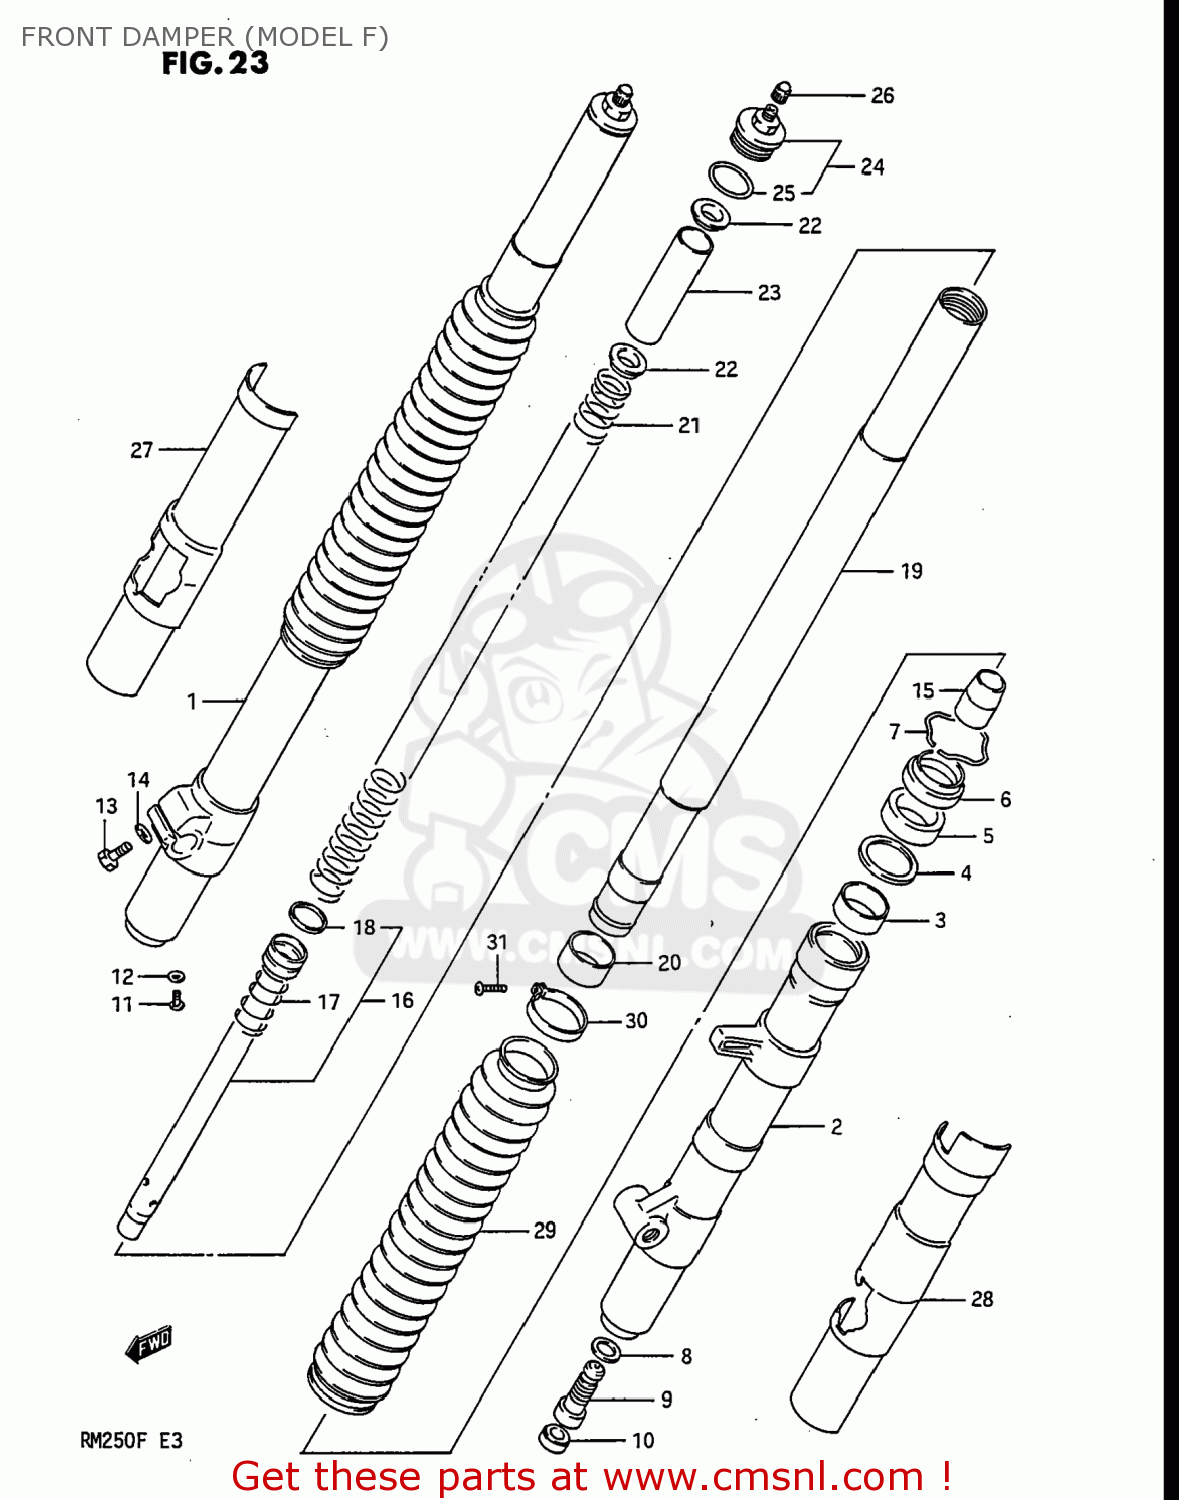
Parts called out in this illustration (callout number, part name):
1	TUBE,OUTER,RIGHT
2	TUBE,OUTER,LEFT
3	METAL,SLIDE
4	WASHER
5	SEAL,OIL
6	SEAL,DUST
7	RING,STOPPER
8	GASKET,FORK CYLINDER
9	VALVE,DF
10	CAP,FRONT FORK DF
11	SCREW 4X6
12	GASKET,DRAIN,PLUG (NAS)
13	BOLT (8X30)
14	WASHER,LOCK,8.
15	PIECE,FRONT FORK OIL LOCK
16	CYLINDER,FRONT FORK
17	SPRING,REBOUND
18	RING,FRONT FORK PISTON
19	TUBE,FORK,INNER
20	PISTON
21	SPRING,FRONT FORK
22	GUIDE,FRONT FORK SPRING
23	SPACER,FRONT FORK SPRING
24	CAP,FORK INNER TUBE
25	O RING
26	CAP
27	PROTECTOR,RIGHT
28	PROTECTOR,LEFT
29	BOOT,FRONT FORK COVER
30	BAND,BOOT,UPPER
31	SCREW 4X10
